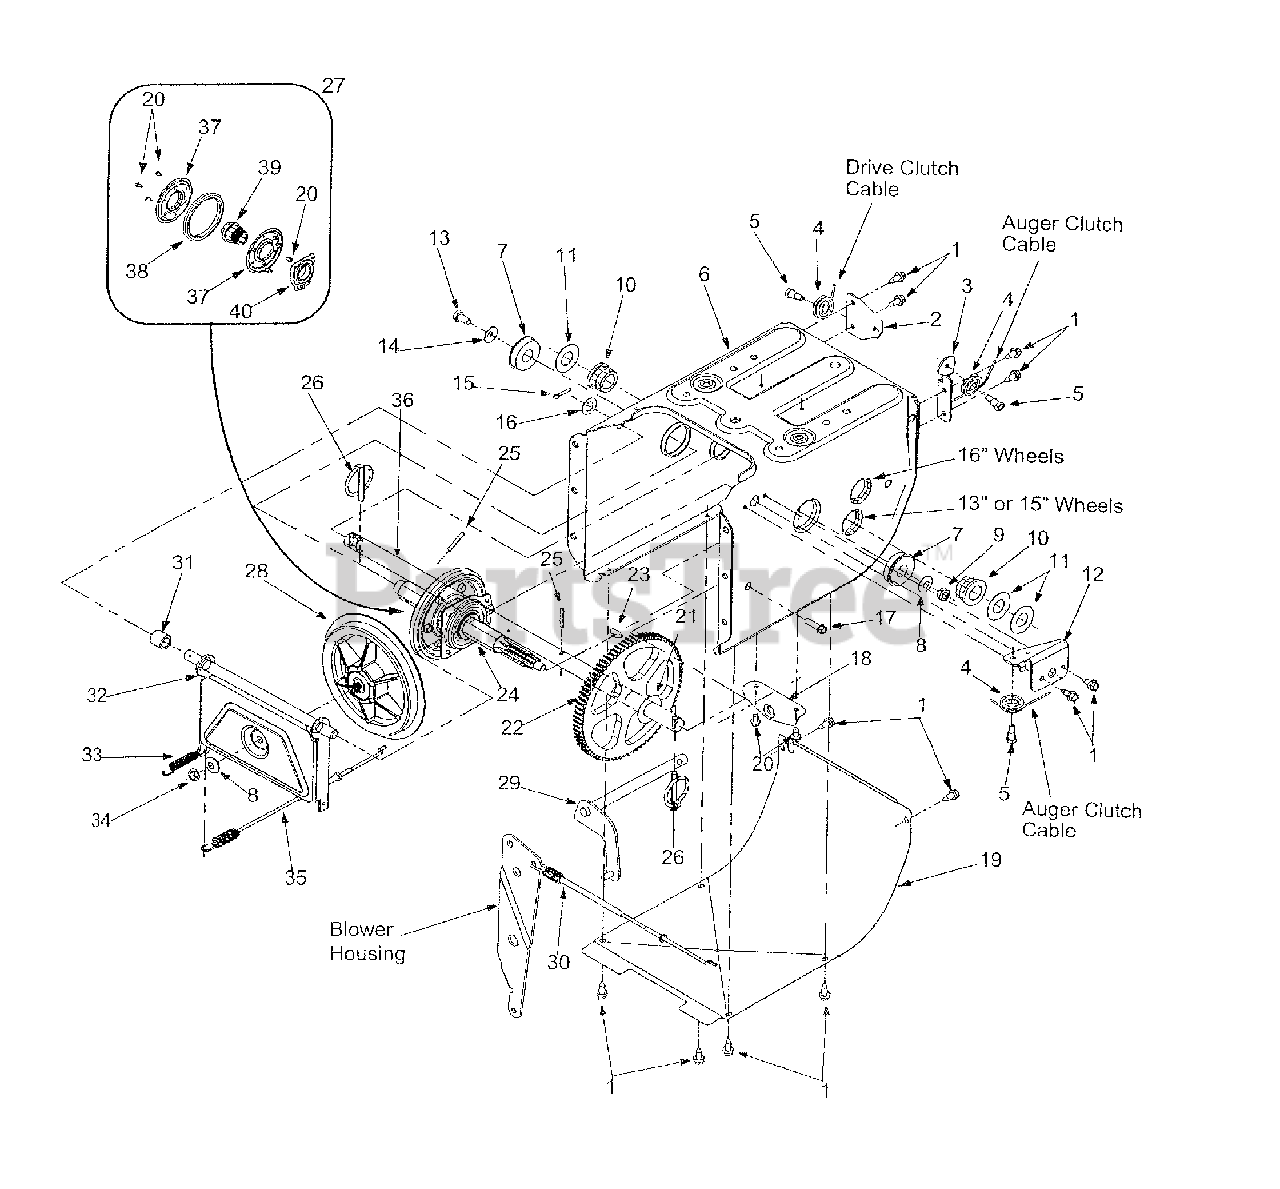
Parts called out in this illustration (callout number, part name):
1	Hex Screw
2	Drive Cable Guide Bracket
3	Auger Clutch Cable Bracket
4	Roller Cable
5	Hex Screw 1/4-28
8	Bell Washer
9	Lock Jam Nut
10	Hex Flange Bearing
11	Flat Washer
12	Front Support Guide Bracket
13	Lock Hex Screw
14	Bell Washer .340 ID x .872 OD
15	Cotter Pin
16	Flat Washer .536 ID x .930 OD
17	Hex Washer Screw 1/4-20
21	Flat Washer .760 ID x .50 OD
23	Key
24	7-Tooth Shaft
25	Roll Pin
26	Klik Pin
27	Friction Wheel Assembly
28	Friction Disc Wheel
29	Wheel Shift Rod Assembly
30	Drive Cable
31	Spacer
32	Friction Wheel Bracket Assembly
33	Extension Spring
34	Jam Nut 3/8-24
35	Drive Cable
36	Axle 13" Wheels
36	Axle 16" Wheels
37	Friction Plate
38	Friction Wheel Rubber
39	Friction Wheel Hub
40	Friction Wheel Bearing
